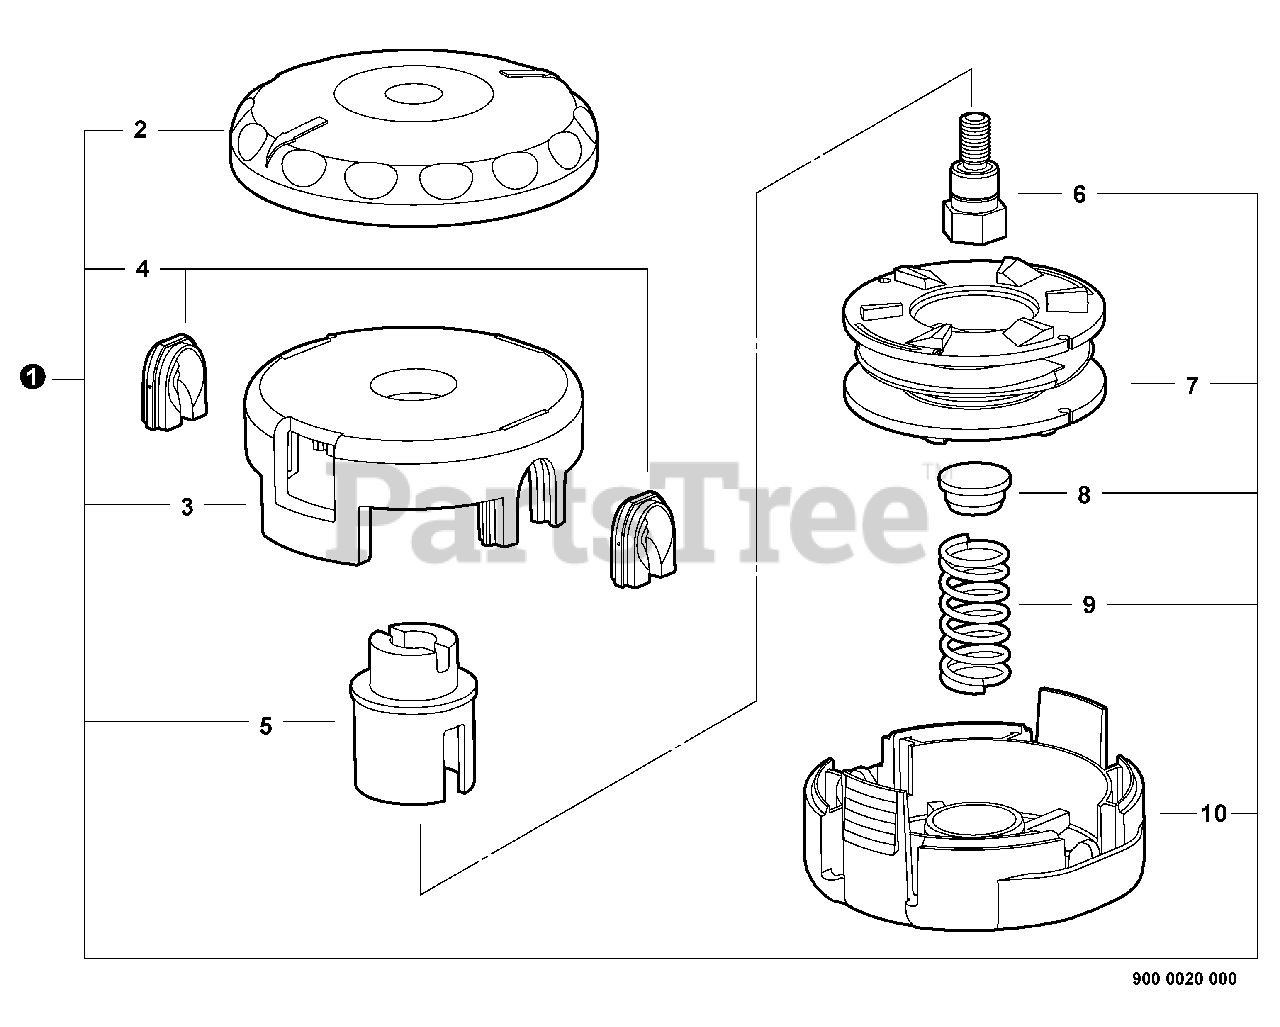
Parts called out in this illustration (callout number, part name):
1	SPEED-FEED 450 TRIMMER HEAD
3	COVER, SPOOL
8	CAP
9	SPRING
